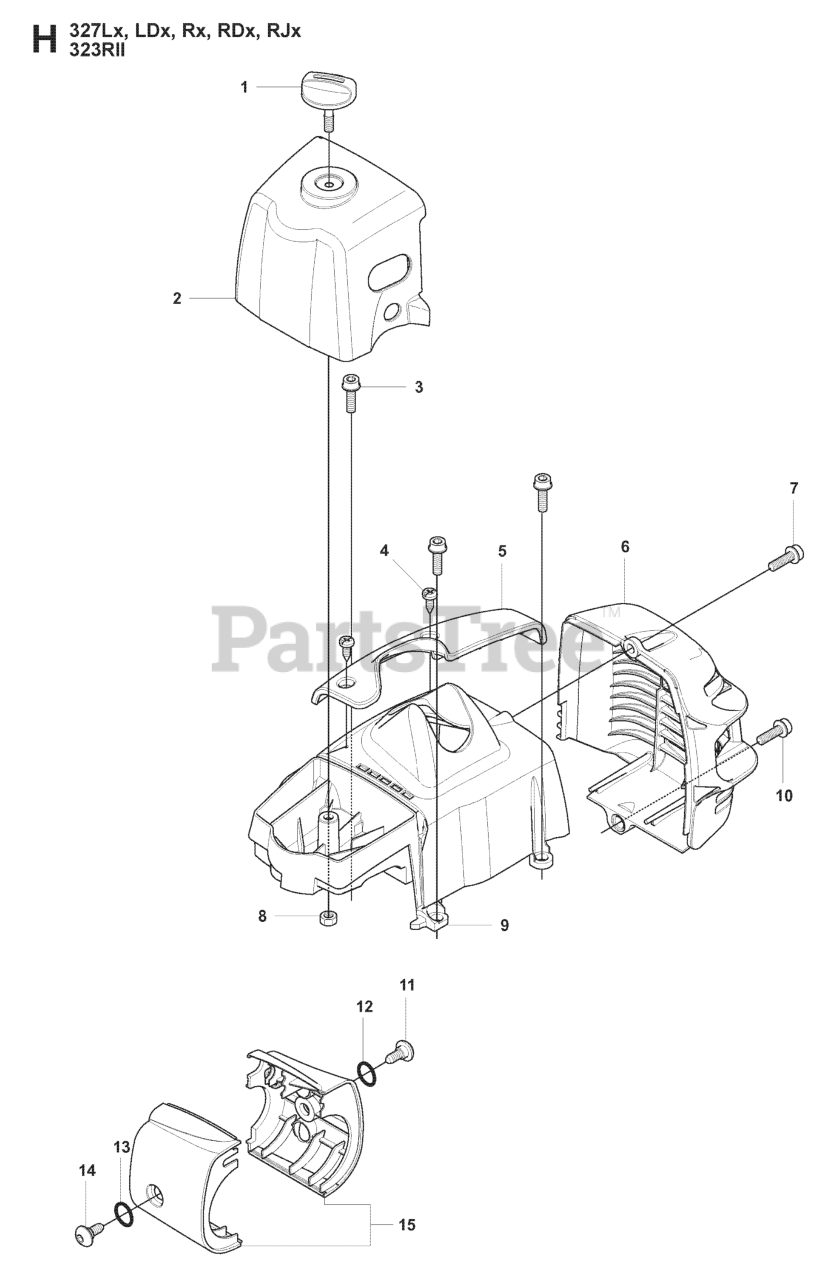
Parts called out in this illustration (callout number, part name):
2	FILTER COVER
5	ARM PROTECTION
6	RP HEAT PROTECTOR
7	SCREW
9	RP CYLINDER COVER
11	SCREW MT5X11
12	O-RING 8X1.6
13	O-RING 8X1.6
14	SCREW MT5X11
